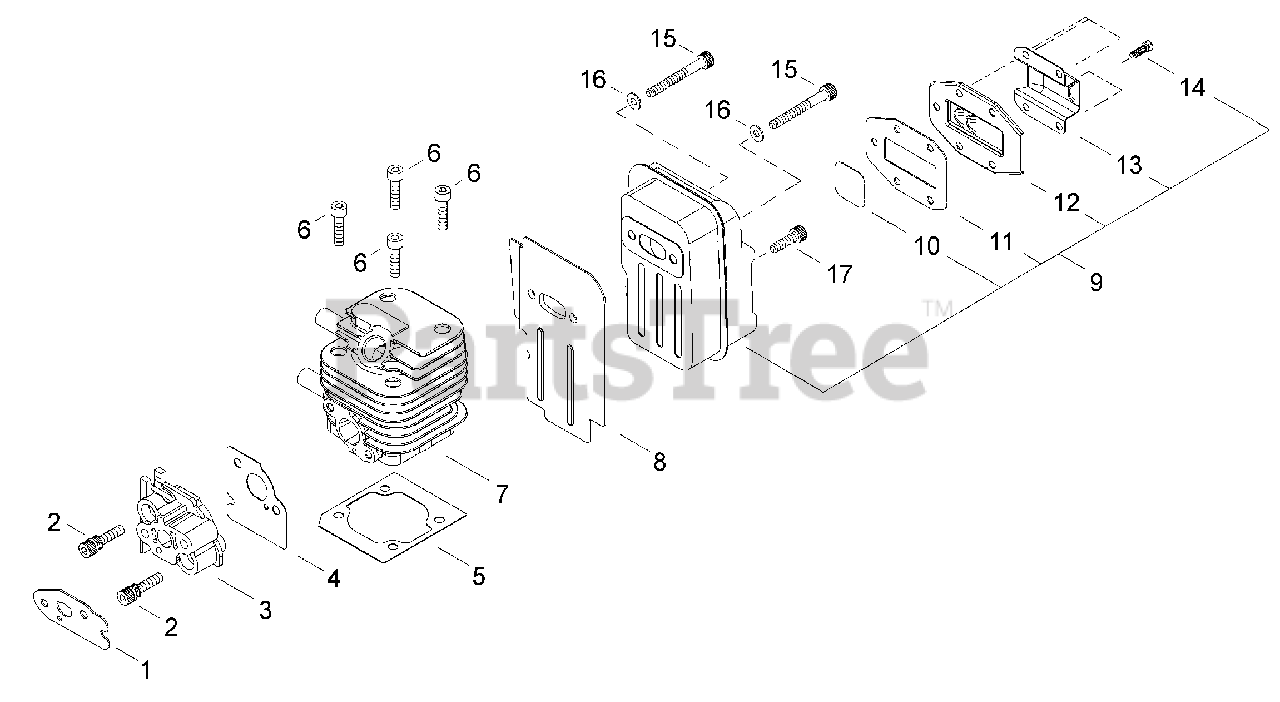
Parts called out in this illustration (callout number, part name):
1-1	GASKET, INTAKE
2	SCREW - 5X30
3	INSULATOR
4	GASKET, INSULATOR
5	GASKET, CYLINDER
6	SCREW - 5X16
7	CYLINDER
8	SHIELD, EXHAUST
9	MUFFLER ASSY
10	SCREEN, SPARK ARRESTOR
11	GASKET, EXHAUST
12	COVER, SCREEN
13	GUIDE, EXHAUST - OUTER
14	SCREW - 4X8
15	SCREW - 5X55
16	WASHER - 5
17	SCREW - 5X12
